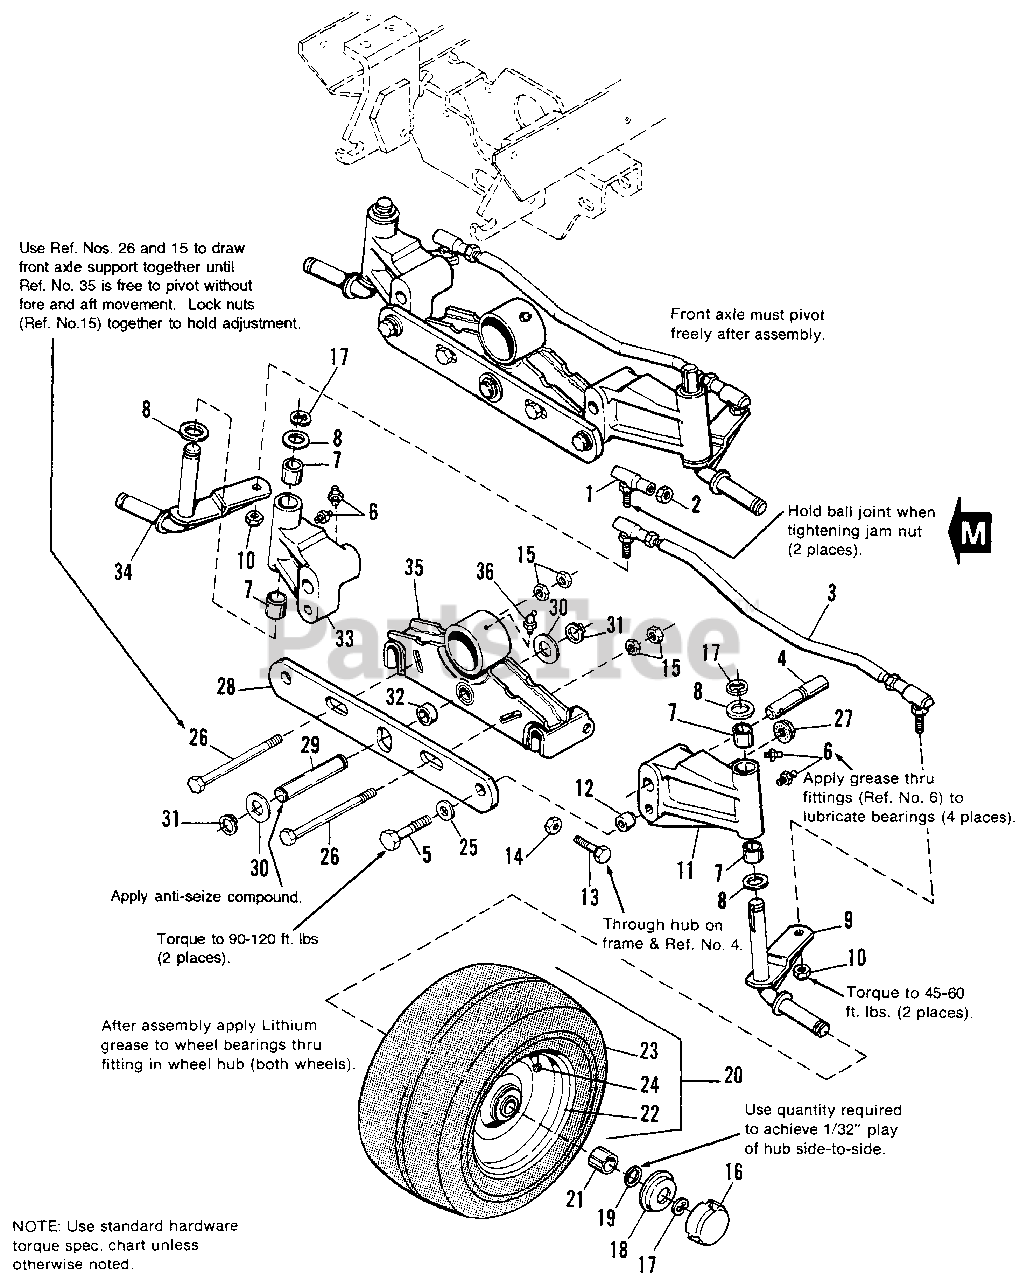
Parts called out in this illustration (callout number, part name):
1	BALL JOINT ASSY.
2	NUT, Hex, Jam, 1/2-20
3	TIE ROD ASSY. (Incl. Ref. No. 1 & 2)
4	PIN, Axle Pivot
5	CAPSCREW, Special Hi Strength, 1/2-13 x 2-3/4
6	FITTING, Lube, 1/4-28
7	BUSHING, Spindle
8	WASHER, 1-1/32 x 1-5/8 x 1/16
9	SPINDLE ASSY., L.H.
10	NUT, Hex, Centerlock, 1/2-20
11	AXLE PIVOT ASSY., L.H. (Incl. Ref. Nos. 6 & 7)
12	SPACER, Axle Link
13	CAPSCREW, Hex Hd., 5/16-18 x 1-3/4, Gr. 5
14	NUT, Hex, Centerlock, 5/16-18
15	Nut, Hex, 3/8-16
17	RING, Retainer
18	RETAINER, Hub Cap
19	WASHER, Shim, 1" I.D. x 1-5/8" O.D. x 1/32" (Use as Required-Qty.)
20	FRONT WHEEL & TIRE ASSY., 16 x 6.50-8 (Incl. Ref. Nos. 22. 23 & 24)
21	BEARING
22	WHEEL ASSY., w/Bearings (Incl. Ref. No. 21)
23	TIRE, 16 x 6.50-8
24	VALVE STEM & CAP
25	WASHER, Heat Treated
26	CAPSCREW, Hex Hd., 3/8-16 x 4
27	NUT, Hex, Flange Lock, 1/2-13
30	WASHER, 3/4
31	RING, Retaining, 3/4
33	AXLE PIVOT ASSY., R.H. (Incl. Ref. Nos. 6 & 7)
34	SPINDLE ASSY., R.H.
35	HITCH SUPPORT ASSY.
36	FITTING, Lube, 45, 1/4", Drive Type
